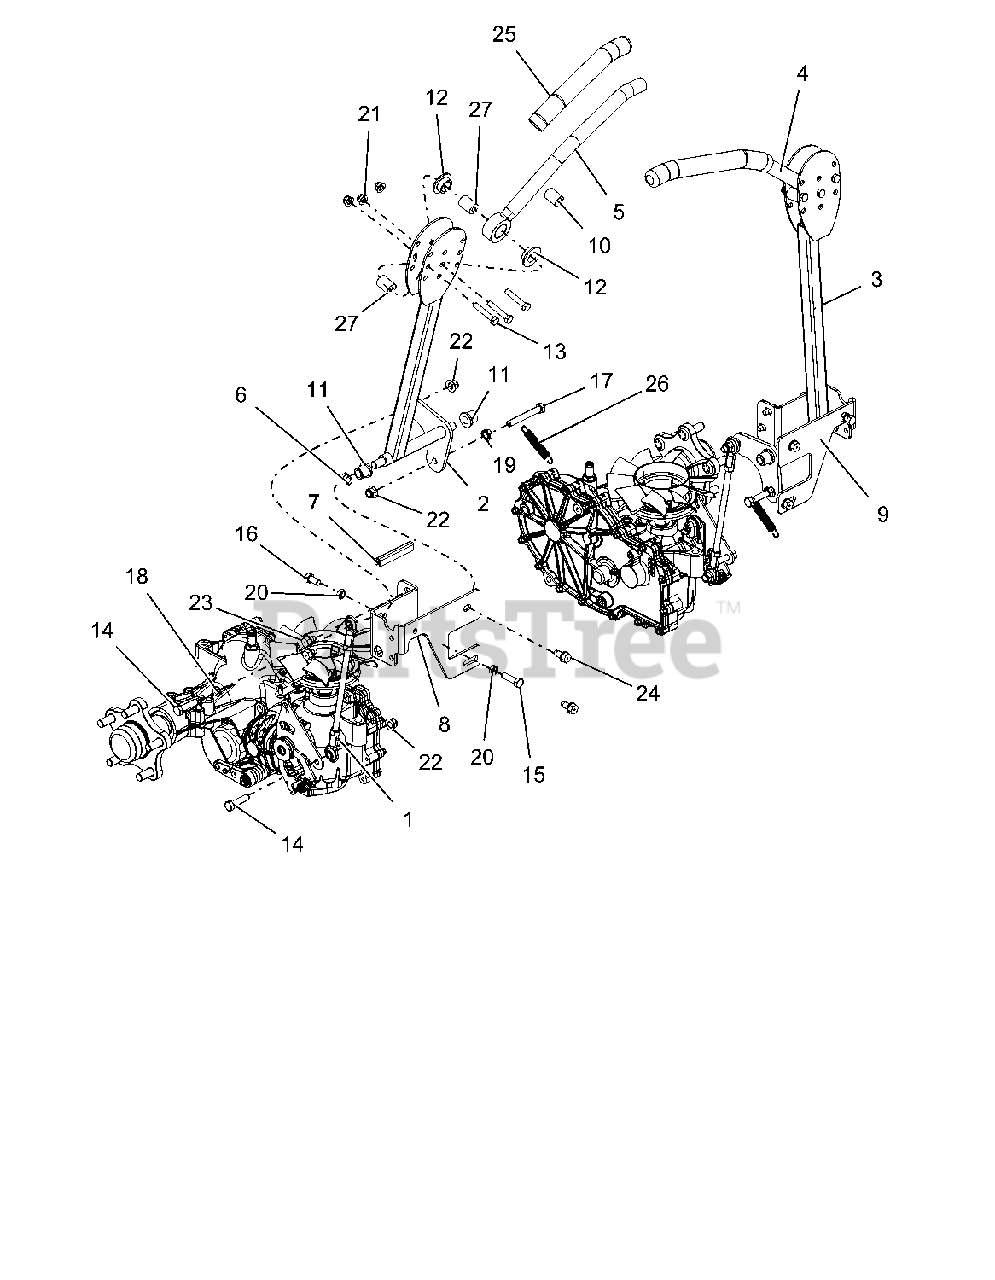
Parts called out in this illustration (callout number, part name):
1	ASM, STEERING LINKAGE
2	WLDMT, PT/PT100 CONTROL ARM-BLACK
3	WLDMT, LH PT/PT100 CONTROL ARM
4	WLDMT, LH HANDLE
5	WLDMT, RH HANDLE
6	WAVE WASHER .531X.781X.125 FH
7	STRIP, COWL - 1.50 LG
8	BRKT, RH STEERING STOP-BLACK
9	BRKT, LH STEERING STOP-BLACK
10	BSHG, ECCENTRIC .328 X .750 X .970
11	BHSG-FLG .500X.750X.750X.125
12	BSHG, FLANGE .762 X 1.48 X .44 NYLON
13	BLT-HEX .31-18X1.75 GR5 YWZC
14	BLT-HEX .38-16X1.50 GR5 YWZC
15	BLT-HEX .38-16X1.25 GR5 YWZC
16	BLT-HEX .38-16X.75 GR5 YWZC
17	BLT-HEX .38-16X2.75 GR5 YWZC
18	WSHR-LK .38X.094 REG YWZC
19	@NUT-SPNLK-FLG .375-16 YWZC
20	NUT, JAM .375-16 YWZC
21	NUT-LK-NYL-FLG .31-18 YWZC
22	NUT-LK-NYL-FLG .38-16 YWZC
23	SCR-TAP .38-16X.50 HWH TR YWZ
24	SCR-TAP .38-16X.75 HWH TR YWZ
25	GRIP, HANDLEBAR .750 ID X 11.125 LG
26	SPRG, EXTENSION
27	SPACER, .328 X .76 X 1.01
